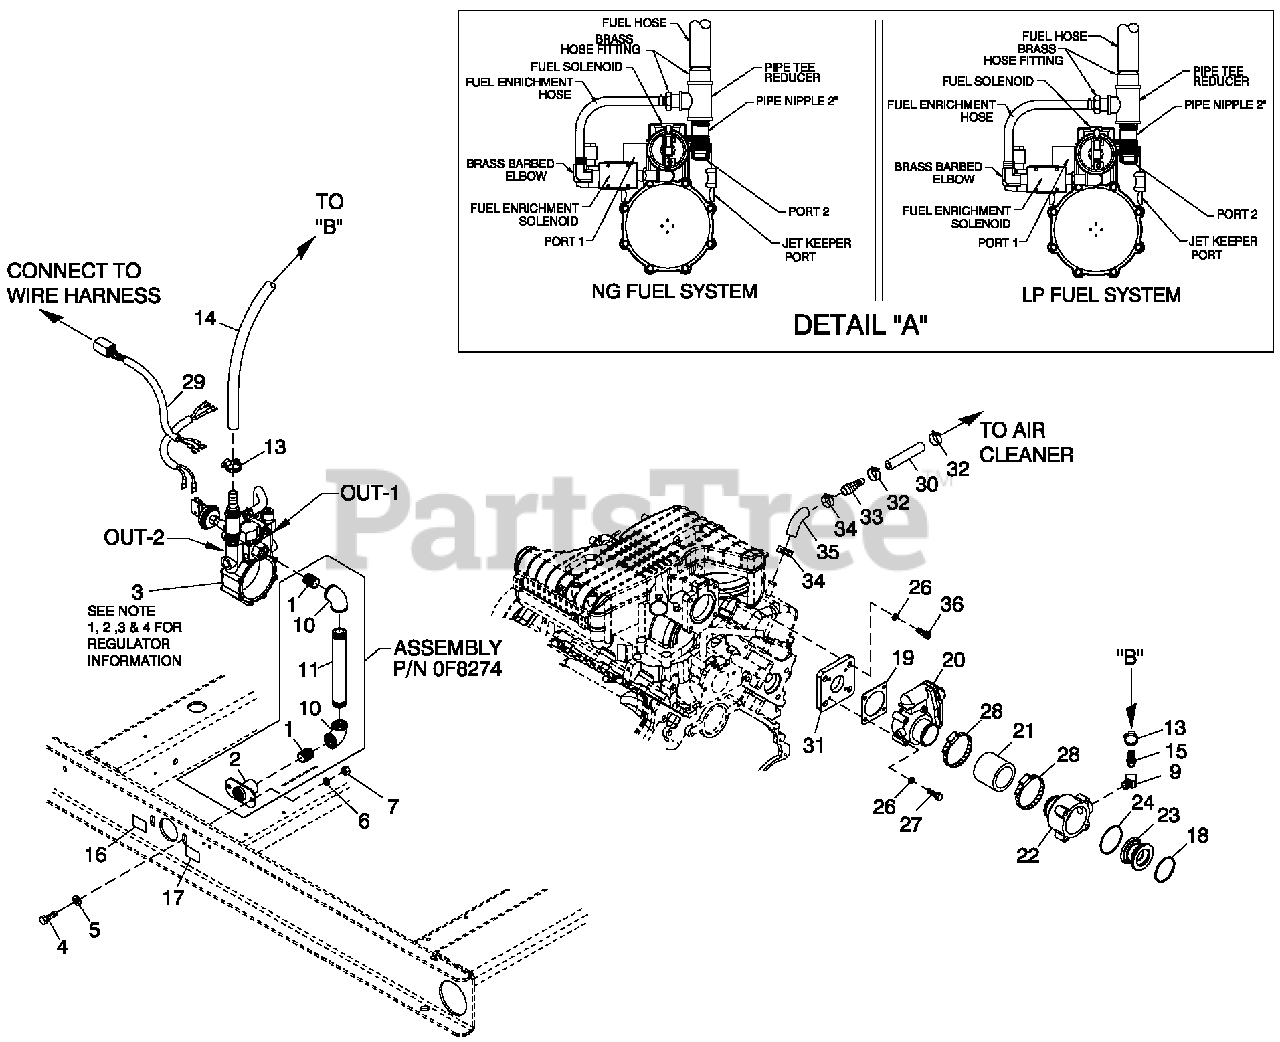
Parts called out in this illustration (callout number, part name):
1	NIPPLE CLOSE 3/4X1.375
2	FLANGE FUEL INLET
3	REGULATOR ASSY 4.2L 48KW
4	SCREW H H CM 8-1.25X 20 G8.8
5	WASHER FLAT 5/16-M8 ZINC
6	WASHER LOCK M8-5/16
7	NUT HEX M8-1.25 G8 CLEAR ZINC
9	STREET EL 45D 1/2 NPT BRASS
10	ELBOW 90D 3/4 NPT
11	NIPPLE P PE 3/4 NPT X 7
13	CLAMP HOSE #10 .5 6 -1 .06
14	HOSE 3/4 D SAE-30R2 (22" LG)
15	BARBED STR 1/2 NPT X 3/4
16	DECAL INLET PRESSURE
17	DECAL FUEL INLET NG (NATURAL GAS APPLICATION)
18	O-RING 45.63 ID X 2.62 WIDT
19	GASKET BOSC 32
20	ACTUATOR BOSC 40 GOVERNOR
21	HOSE COOL 2 IN ID 20R4
22	MiXER ACTUATOR 40MM MACHINED
23	VENTURI THROTTLE 26MM
24	O-RING 47.625 ID X 2.38 W DT
26	WASHER LOCK M6-1/4
27	SCREW S C M6-1.0 X 45 G12.9
28	CLAMP OSE #28 1.32-2.25
29	HARNESS CPL FUEL JUMPER
30	HOSE 3/8 ID S NGLE BRA D (20" LG)
31	INTAKE ADAPTER 4.2L G3-BOSC
32	CLAMP OSE BAND .63
33	HOSE BARB REDUCER 5/8"-3/8" D
34	CLAMP HOSE BAND .88"
35	HOSE COOL 5/8" D 250&WP (2"LG)
36	SCREW S C M6-1.0 X 18 G12.9
